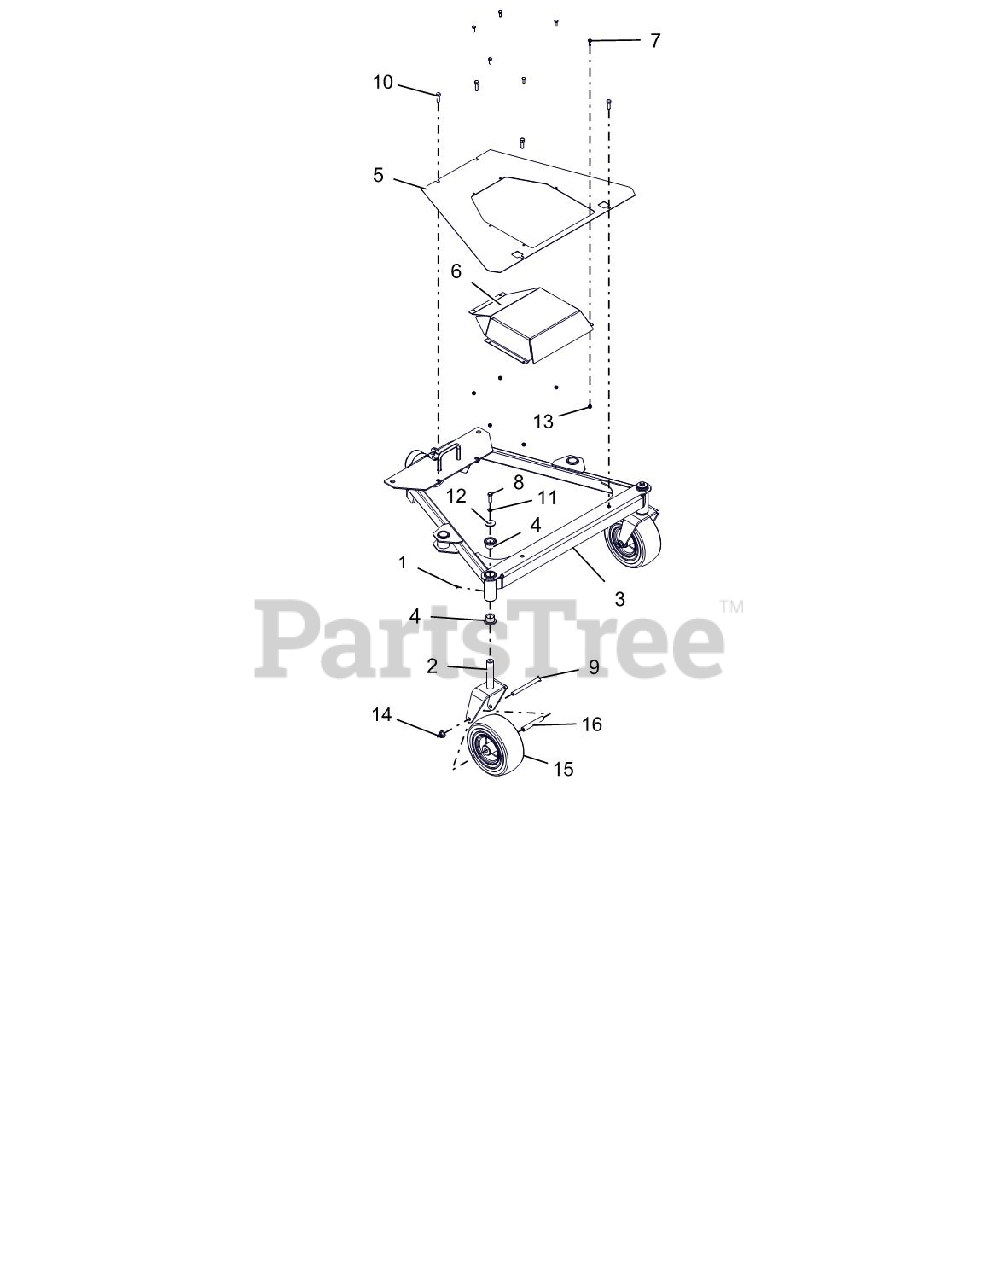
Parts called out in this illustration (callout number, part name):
1	FTG-LUBE .25-28X.256 SST
2	WLDT, FRONT WHEEL FLWLK GRVLY
3	WLDMT, FRAME CARRIER 48" (RED)
4	BRG, FLG 1.00 X 1.25 X 1.00
5	SHIELD, TOP
6	WLDMT, COVER GB
7	BLT, HEX .25-20X.75 GR5 ZC120
8	BLT, HEX .38-16X1.25 G5 ZCC
9	BLT,HEX .50-13X5.50 G5 ZCC
10	BLT, HEX .38-16X1.25 G5 ZCC
11	WSHR-LK .38X.094 REG ZC120
12	WSHR-FL-STL .380X1.50X.125ZC
13	NUT,NYL .25-20 G5 ZCC
14	NUT,LK-NYL-FLG .50-13 G5ZC120
15	ASM, WHL/TIRE 9X3.5-4 CAREFREE
16	TUBE, CASTER AXLE
